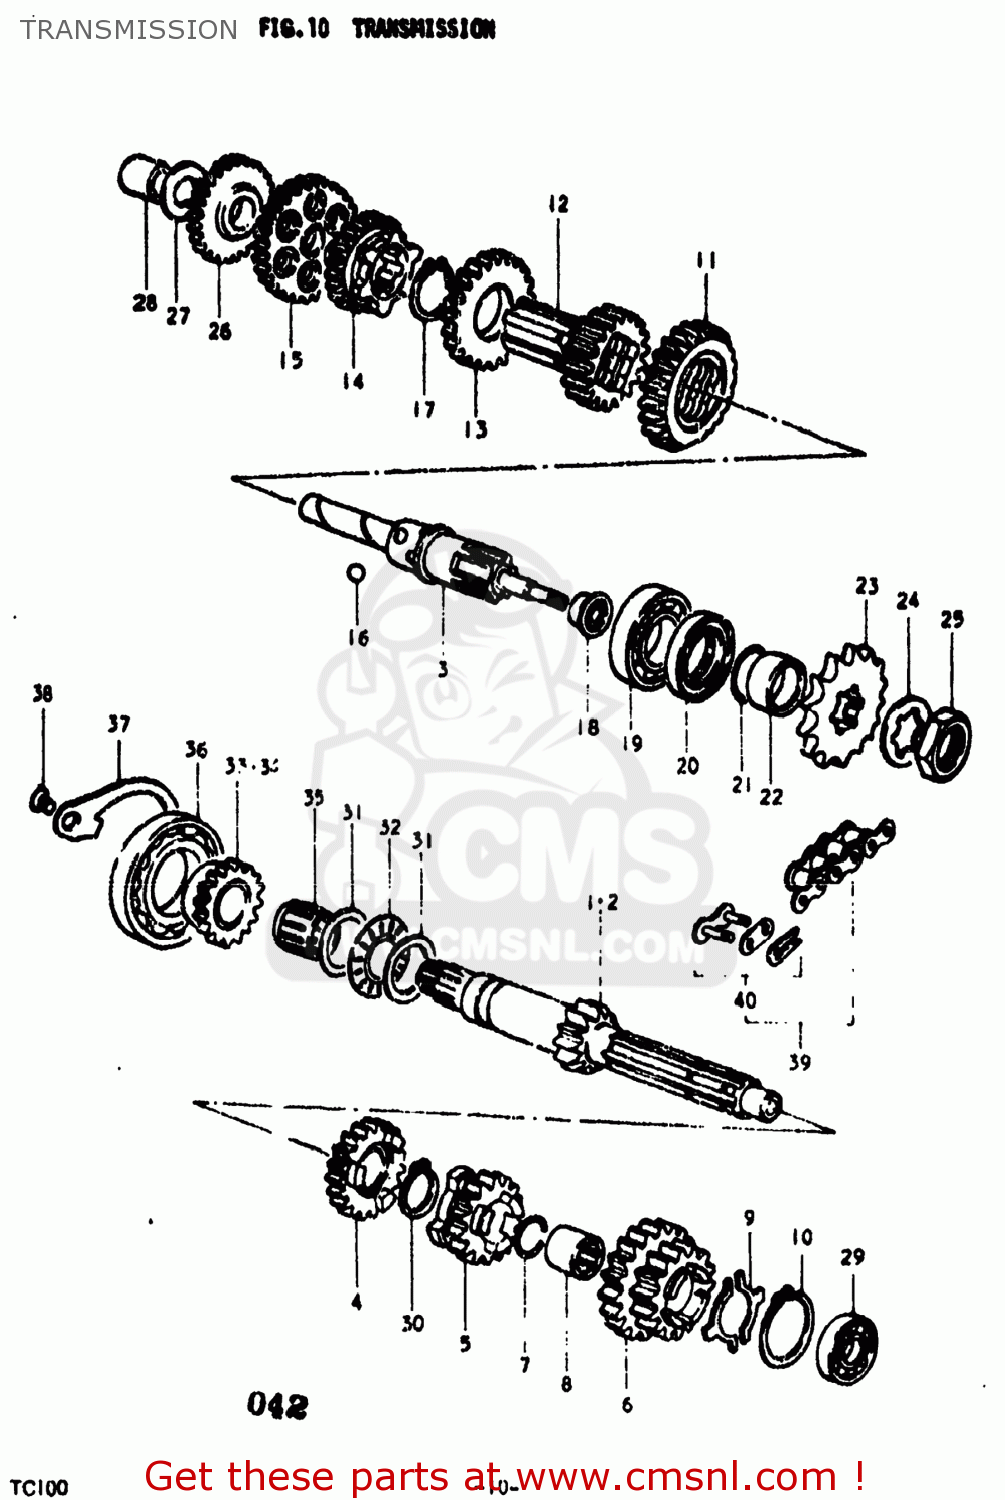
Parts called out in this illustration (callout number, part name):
1	SHAFT,COUNTER
2	SHAFT,COUNTER
3	SHAFT,DRIVE
4	GEAR,THIRD DRIVE
5	GEAR,SECOND DRIVE
6	GEAR,FOURTH DRIVE
7	CIRCLIP
8	SLEEVE,FOURTH PINION
9	KNOCK RING
10	RING,SNAP
11	5TH DRIVEN GEAR
12	GEAR,FOURTH DRIVEN
13	GEAR,SECOND DRIVEN
14	GEAR,THIRD DRIVEN
15	GEAR,FIRST DRIVEN
16	BALL
17	RING,SNAP
18	OIL SEAL
19	BEARING
20	SEAL,OIL(30X44X6)
21	O RING(D:1,ID:24.5)
22	SPACER ENGINE SPROCKET 25X30X13.5
23	SPROCKET,ENGINE
24	WASHER,LOCK
25	NUT
26	GEAR,KICK STARTER IDLE
27	WASHER
28	BUSHING
29	BEARING(12X28X8)
30	CIRCLIP
31	WASHER(21X30X0.8)
32	BEARING 21X35X2.8
33	GEAR,KICK STARTER DRIVEN(NT:16
34	GEAR,KICK STARTER DRIVE
35	BEARING(19.2X23.2X19)
36	BEARING
37	PLATE,COUNTERSHAFT BEARING
38	SCREW
39	CHAIN ASSEMBLY,DRIVE
40	JOINT ASSEMBLY,CHAIN
